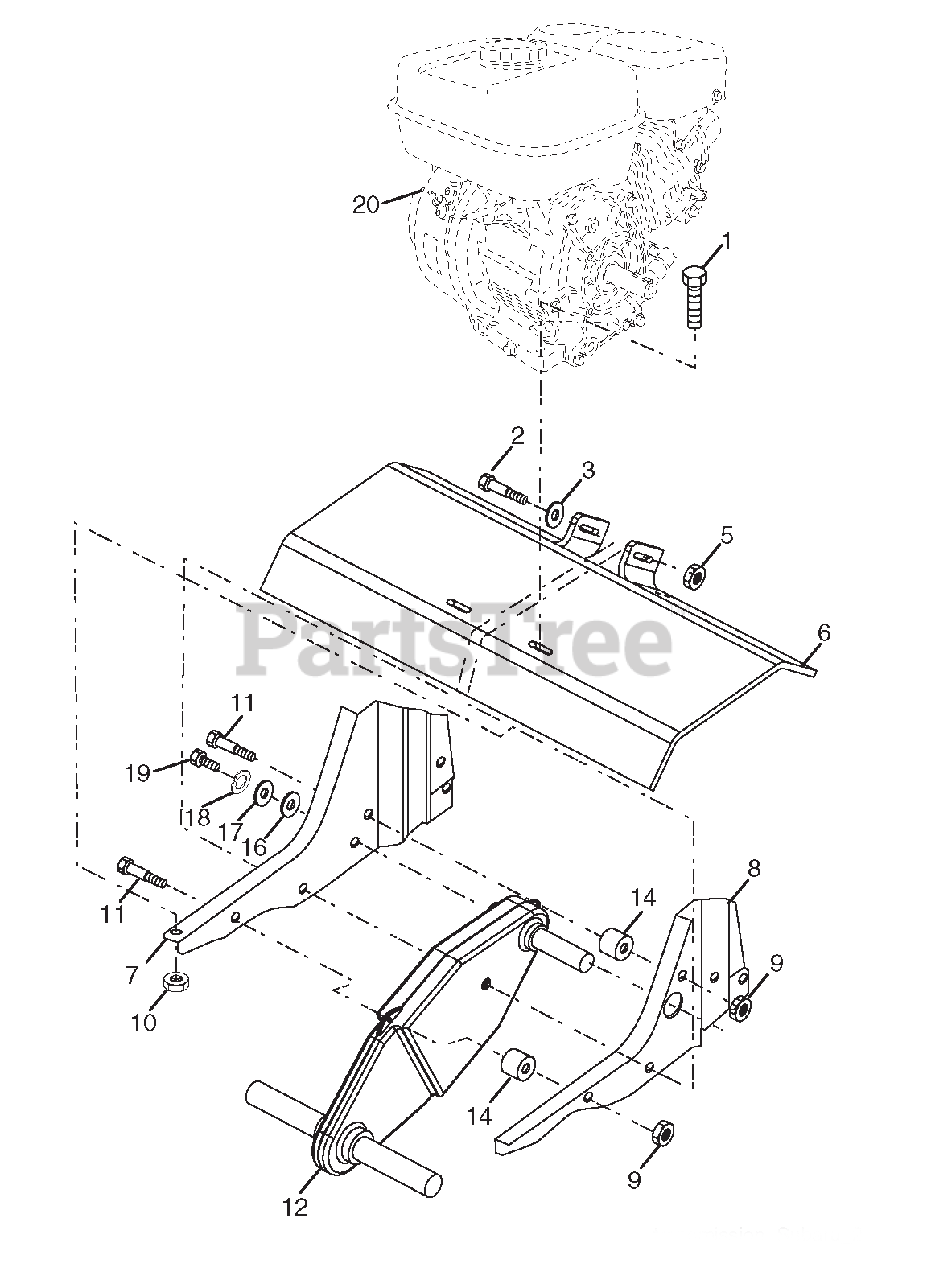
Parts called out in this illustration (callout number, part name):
1	Bolt, Hex Head, Gr. 25/16-18 x
2	Bolt, Hex Head, 3/8-16 x 3-1/4
3	Washer 13/32 x 13/16 x 11 Ga.
5	Nut, Hex, Flangelock 3/8-16
6	SHIELD, TINE
7	Bracket, Engine, R.H.
8	Bracket, Engine, L.H.
9	Nut, Hex
10	Nut, Hex, Flangelock
11	Bolt, Shoulder
12	Transmission
14	SPLIT SPACER
16	Washer, 9/32 x 7/8 x 12 Ga.
17	Washer, 9/32 x 1-1/4 x 16 Ga.
18	Washer, Lock 1/4
19	Bolt, Hex Head, Gr. 51/4-28 x
20	Engine, Subaru, Model Number EX170DT1030 (422996)(Order parts from engine manufacturer.)
